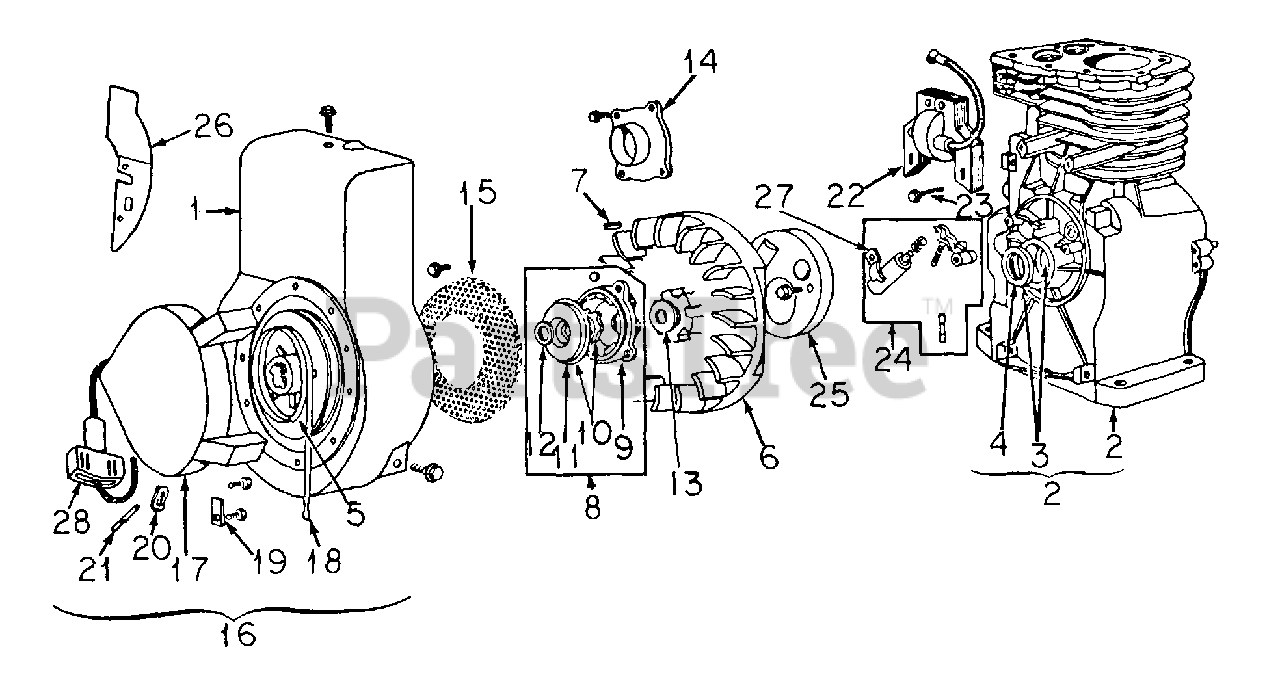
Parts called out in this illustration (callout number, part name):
1	HOUSING, BLOWER
2	CYLINDER ASSY. ENGINE
3	BUSHING AND SEAL
4	SEAL, OIL
5	PULLEY, REWIND STARTER
7	KEY, FLYWHEEL
8	CLUTCH ASSY, REWIND STARTER
9	HOUSING, REWIND STARTER CLUTCH
10	RATCHET, STARTER
11	RETAINER, WASHER
12	SEAL, RATCHET
13	WASHER, SPRING
14	SHIELD, CLUTCH
15	SCREEN, REWIND STARTER
16	STARTER ASSY, REWIND
17	HOUSING, REWIND STARTER
18	SPRING, REWIND STARTER
19	BUMPER, REWIND PULLEY
20	SPRING, ANCHOR INSERT
21	PIN, STARTER GRIP PIN
22	ARMATURE ASSY, MAGNETO
23	SCREW, ARMATURE MOUNTING
24	KIT, IGNITION SERVICE
25	COVER, BREAKER POINT
26	GUARD, FLYWHEEL
27	CLAMP, CONDENSER
28	PACKAGE, REWIND STARTER HANDLE AND INSERT
